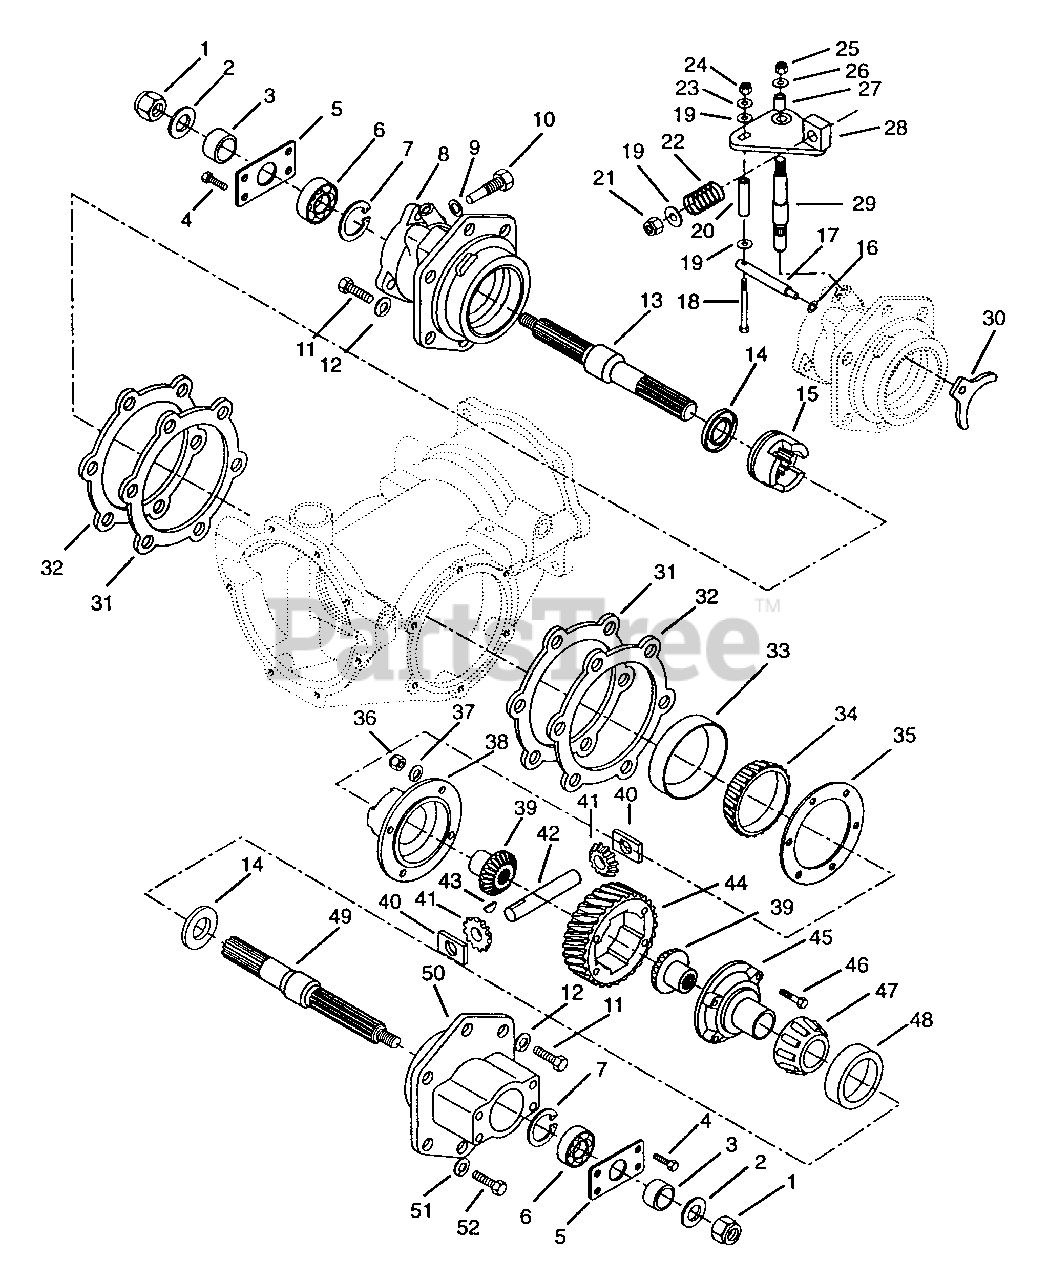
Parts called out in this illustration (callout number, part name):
1	Nut-Locking-Jam-Nylon .75-10
2	Washer-Flat .812 x 1.469 x .134
3	Spacer 1.008 x 1.377 x .509
4	Bolt-Hex.38-16 x.75 Grade 5
5	Plate, End
6	Bearing-Ball 1.0 x 2.0 x .56
7	Ring-Retaining-Internal 2.210 x .062
8	Housing, Axle, 2 Speed
9	Washer-Nut .63 x .875 x .062
10	Bolt-Hex .62-18 x .493 x 1.25
11	Bolt-Hex .50-13 x 1 Grade 5
12	Washer-Lock .50 Reg.
13	Axle, Straight Differential Locking
14	Seal 1.188 x 2.000 x .250
15	Clutch, Sliding Differential Locking
16	O-Ring .437 x .625 x .093
17	Pin, Clutch Sliding
18	Bolt-Round Head Square Neck .25-20 x 2.25 Grade 8
19	Washer-Flat-Steel .406 x .812 x .065
20	Bushing, Sleeve .277 x .375 x 1.37
21	Nut-Locking-Nylon .375-16 Grade 2
22	Spring-Compression .067 x .72 x 2.0
23	Washer-Flat-Steel .281 x .620 x .065
24	Nut-Locking-Nylon .250-20 Grade 2
25	Nut-Locking-Nylon .312-18 Grade 2
26	Washer-Flat-Steel .344 x .688 x .065
27	Bushing-Sleeve .377 x .503 x .88
28	Weldment, Arm Shifter
29	Pivot, Stationary
30	Yoke, Shifting
31	Gasket, Axle Housing
32	Shim, Axle Housing .005
33	Bearing-Race 4.34 x .741
34	Bearing-Cone 2.69 x .87
35	Shim, .005 Clutch Worm Gear
36	Nut-Hex .312-24 Grade 2
37	Washer-Lock Internal .313 x .030
38	Housing, Differential Locking
39	Gear, Differential Bevel
40	Block, Drive
41	Gear, Spider Bevel
42	Pin, Spider Pinion
43	Key-Woodruff .13 x .38
44	Gear, 4-Lead Worm
45	Housing, Differential
46	Bolt-Hex .31-24 x 2.75
47	Cone Roller Bearing 50 MM x 21.5 MM
48	Cup, Roller Bearing 82 MM x 17 MM
49	Axle, Straight
50	Housing, Axle
51	Seal-Oil Drain .563 x 1.250 x .091
52	Bolt-Hex .50-13 x 1.312 Grade 5
